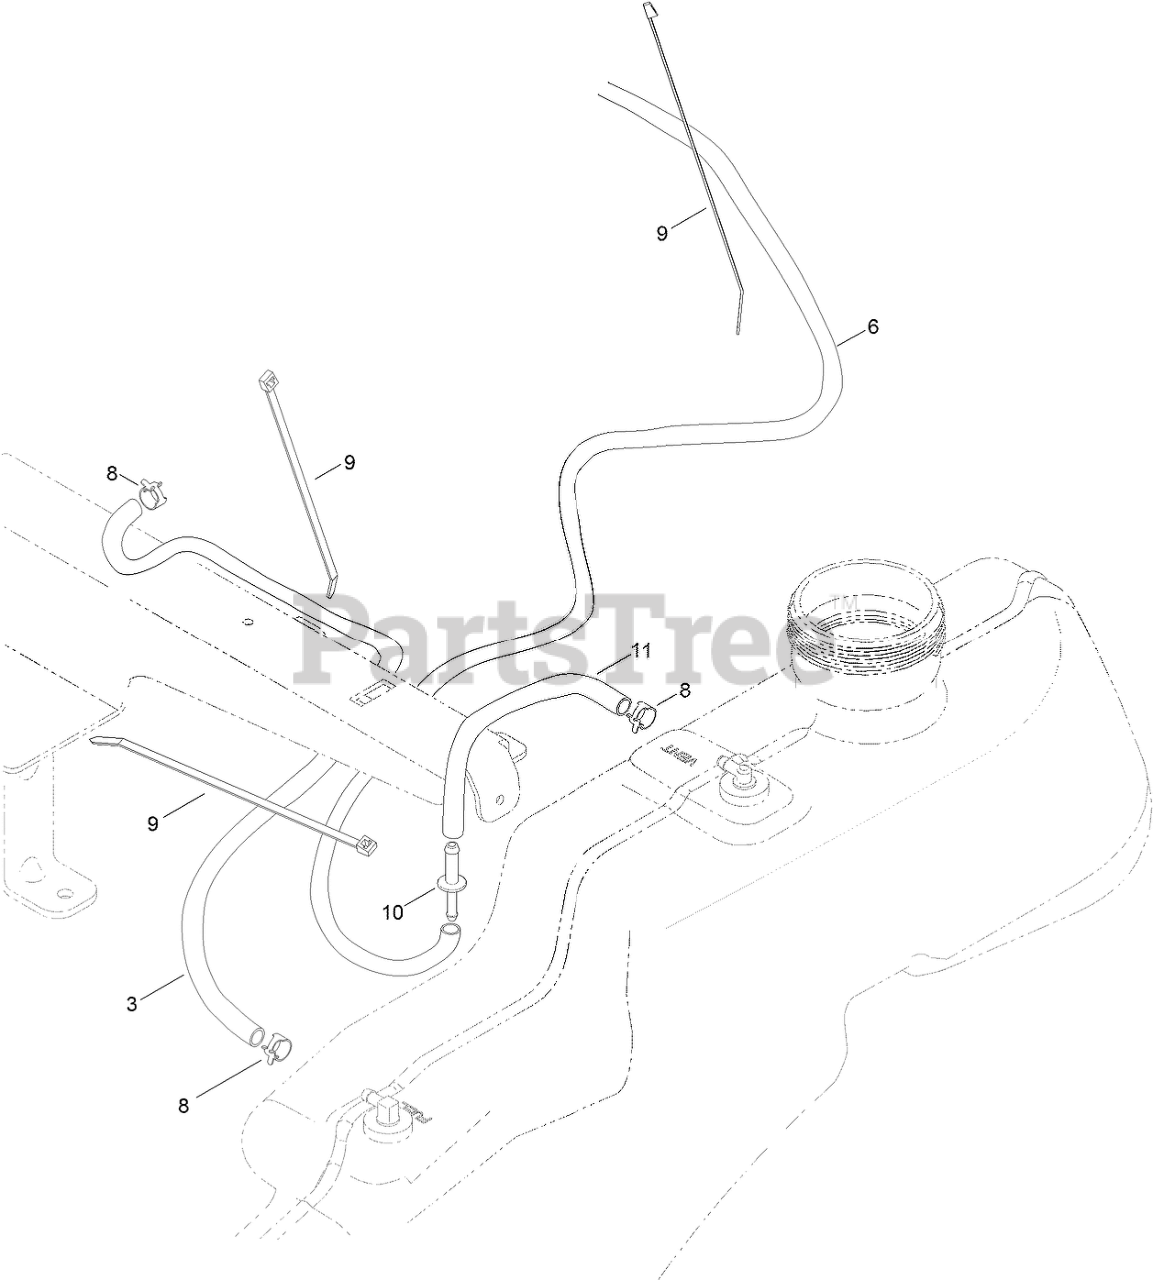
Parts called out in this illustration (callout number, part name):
3	HOSE-FUEL
6	HOSE-FUEL
8	CLAMP-HOSE
9	TIE-CABLE
10	ADAPTOR-ORIFICE
11	HOSE-FUEL
